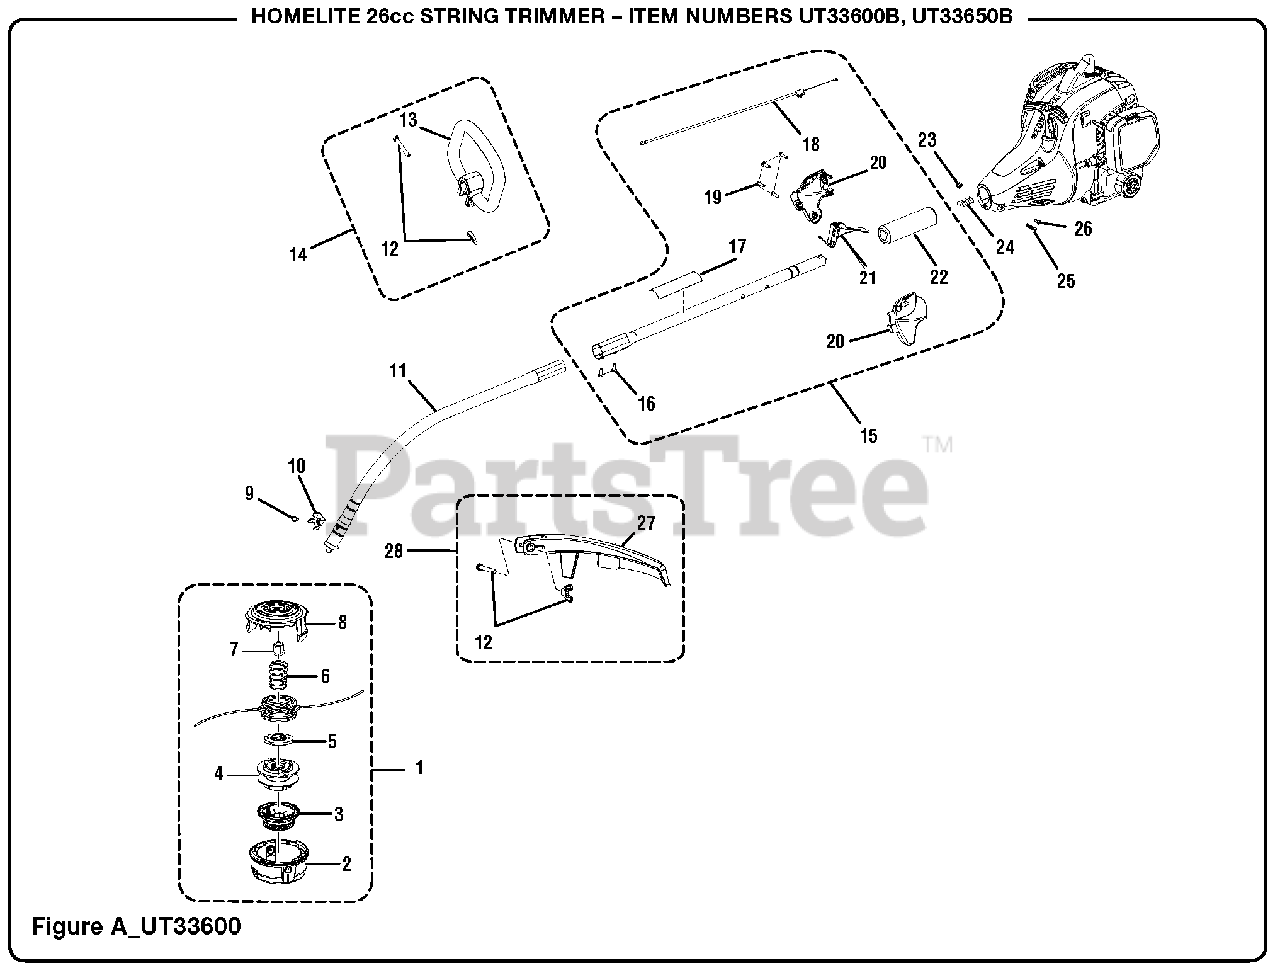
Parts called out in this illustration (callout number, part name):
1	Trimmer Head Assembly
2	Lower Housing
3	Bump Knob (Gray)
5	String Guide
6	Compression Spring
7	Hex Nut (M8)
8	Upper Housing
9	Screw (10-32 x 3/8 in., Hex Hd.)
11	Lower Boom Assembly
12	Fastener Kit
13	Front Handle
14	Front Handle Assembly
15	Boom Assembly
16	Screw (M5 x 10 mm, Hex. Soc. Hd.)
17	Icon Warning Label
18	Throttle Cable
19	Screw (M4 x 20 mm, T20 Torx Pan Hd. T.F.)
20	Trigger Handle Assembly
21	Throttle Trigger
22	Foam Grip
23	Hex Nut (M6)
24	Compression Spring
25	Screw (M6 x 20 mm, T27 Torx Button Hd.)
26	Screw (M4 x 8 mm, T20 Torx Round Hd.)
27	Grass Deflector
28	Grass Deflector Assembly
